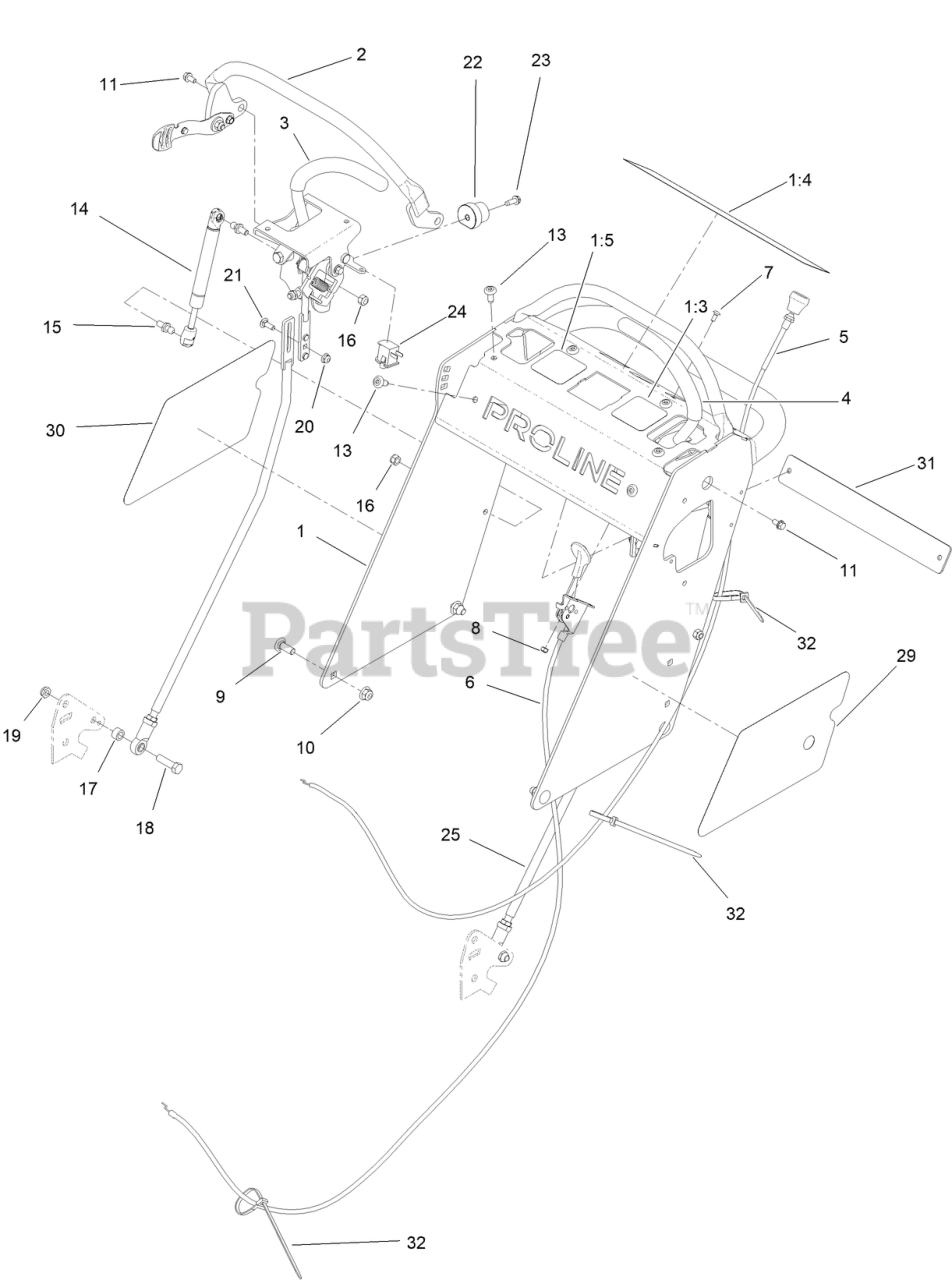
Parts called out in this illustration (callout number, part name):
1	TOWER ASM
1:3	DECAL-OPC CONTROL, LEFT
1:4	DECAL-WARNING, CONTROL
1:5	DECAL-OPC CONTROL, RIGHT
2	REFERENCE BAR ASSEMBLY
3	CONTROL HANDLE ASM, RH
4	CONTROL HANDLE ASM, LH
5	CABLE, CHOKE
6	CONTROL-THROTTLE
7	SCREW-CARR
8	NUT-LOCK, NI
9	SCREW-CARR
10	NUT-HF, NI
11	SCREW-HWH
14	DAMPER
15	STUD-BALL
16	NUT-LOCK, NI
17	SPACER
18	SCREW-HH
20	NUT-HF
21	BOLT-CARR
23	SCREW-HWHTF
24	SWITCH-BAIL
25	CONTROL ROD ASM
29	DECAL-PROLINE HDX, LH
30	DECAL-PROLINE HDX, RH
31	PLATE-COVER
32	TIE-CABLE
